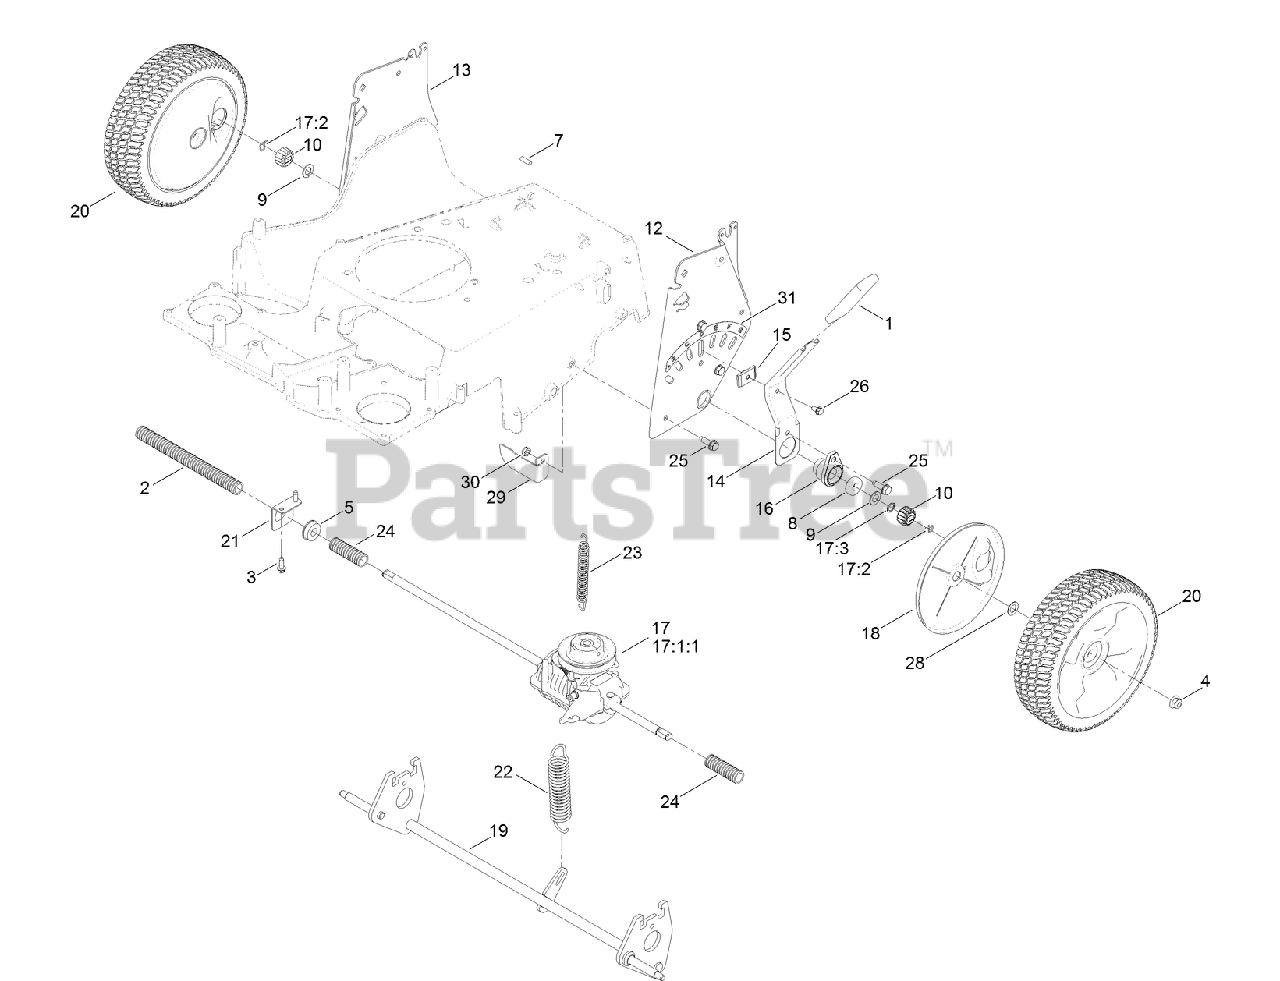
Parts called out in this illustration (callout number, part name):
1	GRIP-LEVER, LIFT
2	CONDUIT-CONVOLUTED
3	SCREW-HWHTF
4	NUT-HF, NI
5	BEARING-BALL
7	PIN-STOP
8	BEARING-BALL
9	WASHER-THRUST
10	GEAR-PINION, 15T
12	PLATE-HOC, LH
13	PLATE-HOC, RH
14	ARM-SPRING, REAR
15	KEY-SPRINGARM
16	RETAINER-BEARING
17	TRANSMISSION KIT
17:1:1	TRANSMISSION PULLEY KIT
17:2	PIN-SNAP
17:3	RING-RETAINING
18	COVER-GEAR
19	AXLE-REAR
20	10 INCH WHEEL GEAR ASM
21	MOUNT-BEARING
22	SPRING-EXTENSION
23	SPRING-EXTENSION
24	CONDUIT-CONVOLUTED
25	SCREW-HWHTF
26	SCREW-HWH
28	WASHER-PLAIN
29	BRACKET-STOP
30	NUT-LOCK, NI
31	DECAL-HOC, REAR
